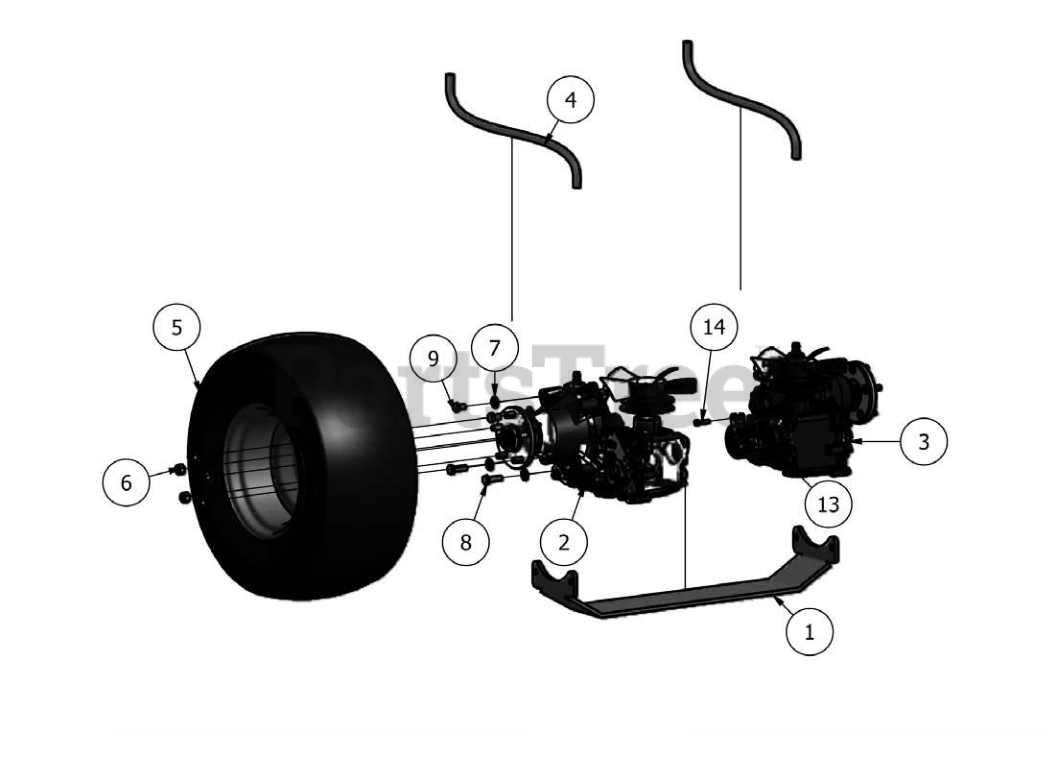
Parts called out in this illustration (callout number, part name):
1	Outlaw TransAxle Cross Brace
2	ZT-5400 - Left
3	ZT-5400- Right
4	1/2 Clear Braided Hose
5	24 x 12 x 10 Tire and Wheel
6	Acorn Lug Nut
7	1/2 Lock Washer Zinc
8	1/2-20 x 1-1/2 Grade 5 Hex Bolt Zinc
9	1/2 x 3/4 Bolt
10	Brake Spring
11	5/16-18 Hex Flange Nuts Zinc w/Serations
12	5/16-18 x 1-3/4 Grade 5 Hex Bolt
13	5/16-18 Nylon Insert Locknut Zinc Orange Nylon
14	5/16-18 x 1-1/4 Grade 5 Hex Bolt
15	24 x 12 x Tire Only
